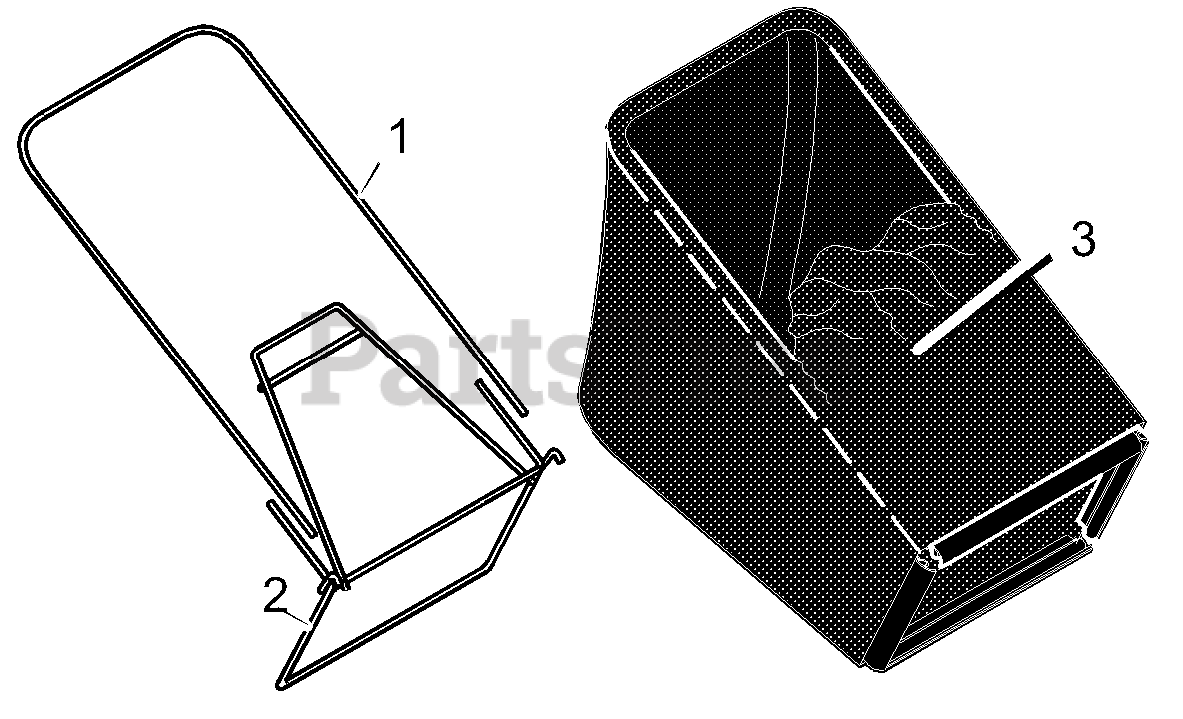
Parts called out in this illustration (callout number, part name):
1	Frame, Top
2	Frame Assy.
3	Bag, Cloth
